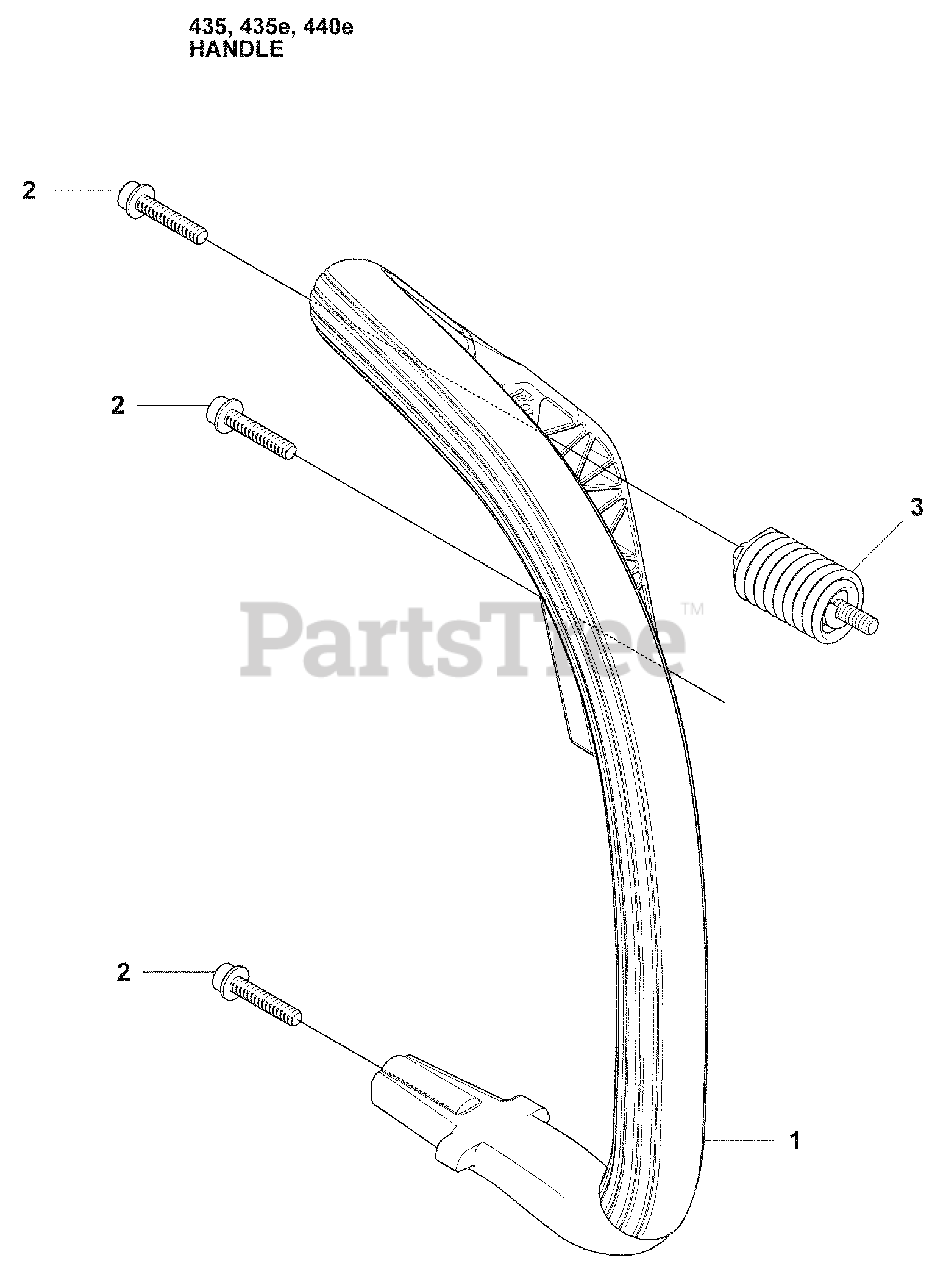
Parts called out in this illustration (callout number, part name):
1	Front Handle
2	Screw, 3 X 25 IHSCFT
3	Insulator
